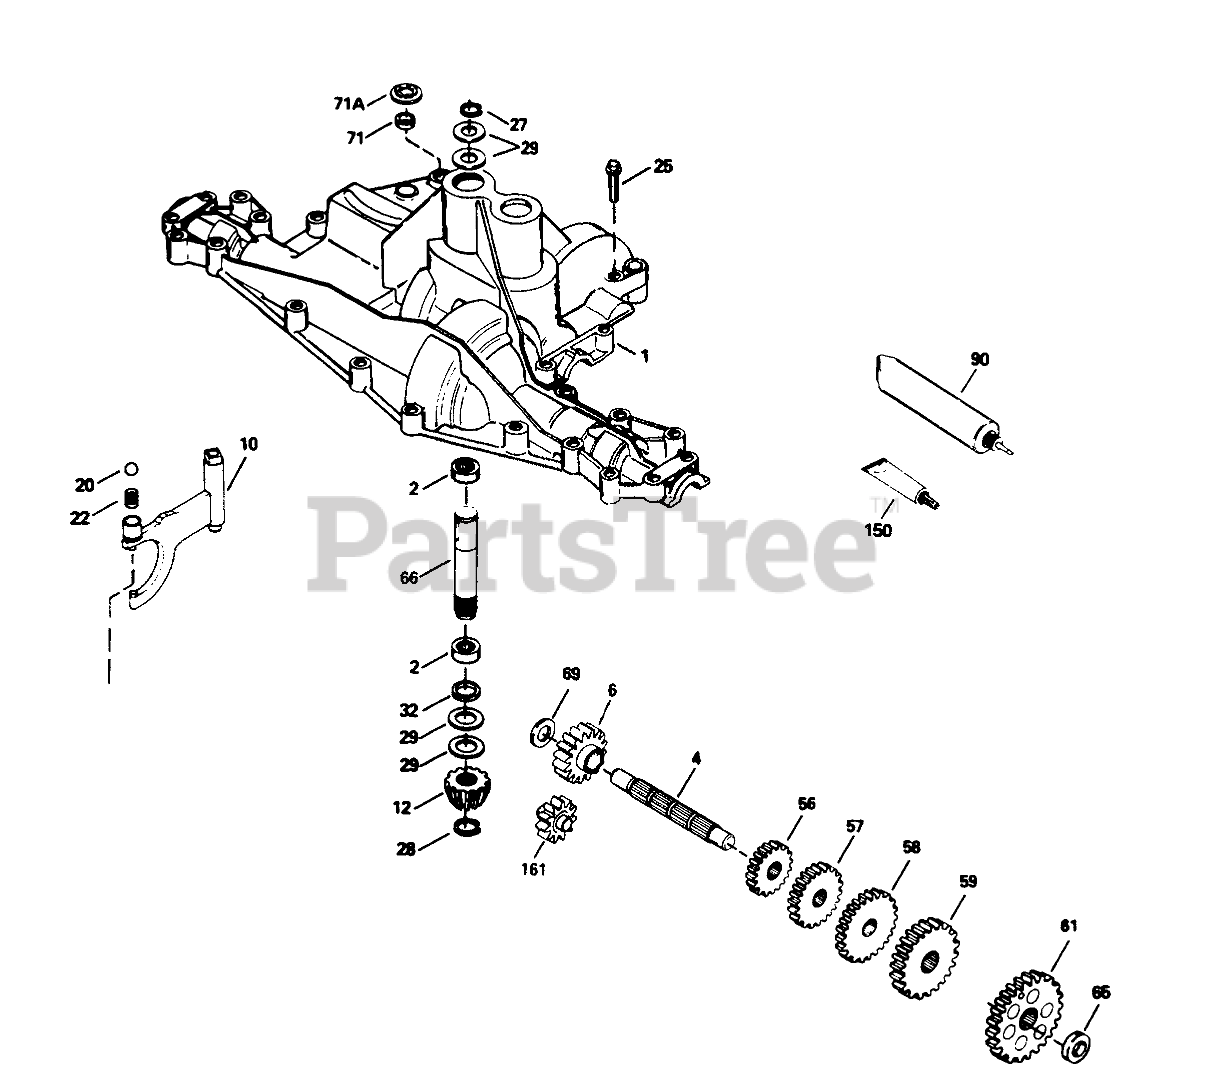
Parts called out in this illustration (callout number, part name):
1	Transaxle Cover
4	Countershaft
6	Spur Gear (16 Teeth)
10	Shift Rod & Fork
12	Bevel Pinion (14 Teeth)
20	Ball (3/8" dia.)
22	Spring
25	Ring Set (.020 O S)
27	Ring-Snap
28	Ring-Retainer
29	Washer
32	O Ring
34	Bushing
56	Gear-Spur, 15 Teeth
57	Gear-Spur 23 Teeth
58	Spur Gear (21 Teeth)
59	Gear-Spur (30 teeth)
61	Spur Gear (34Teeth)
65	Washer
66	Input Shaft (3.522" Ig.)
69	Thrust Washer
71	Cut Seal-Square
71A	Pushnut
90	Grease 32 Oz
150	Gasket Eliminator
161	Reverse Idler Assembly
